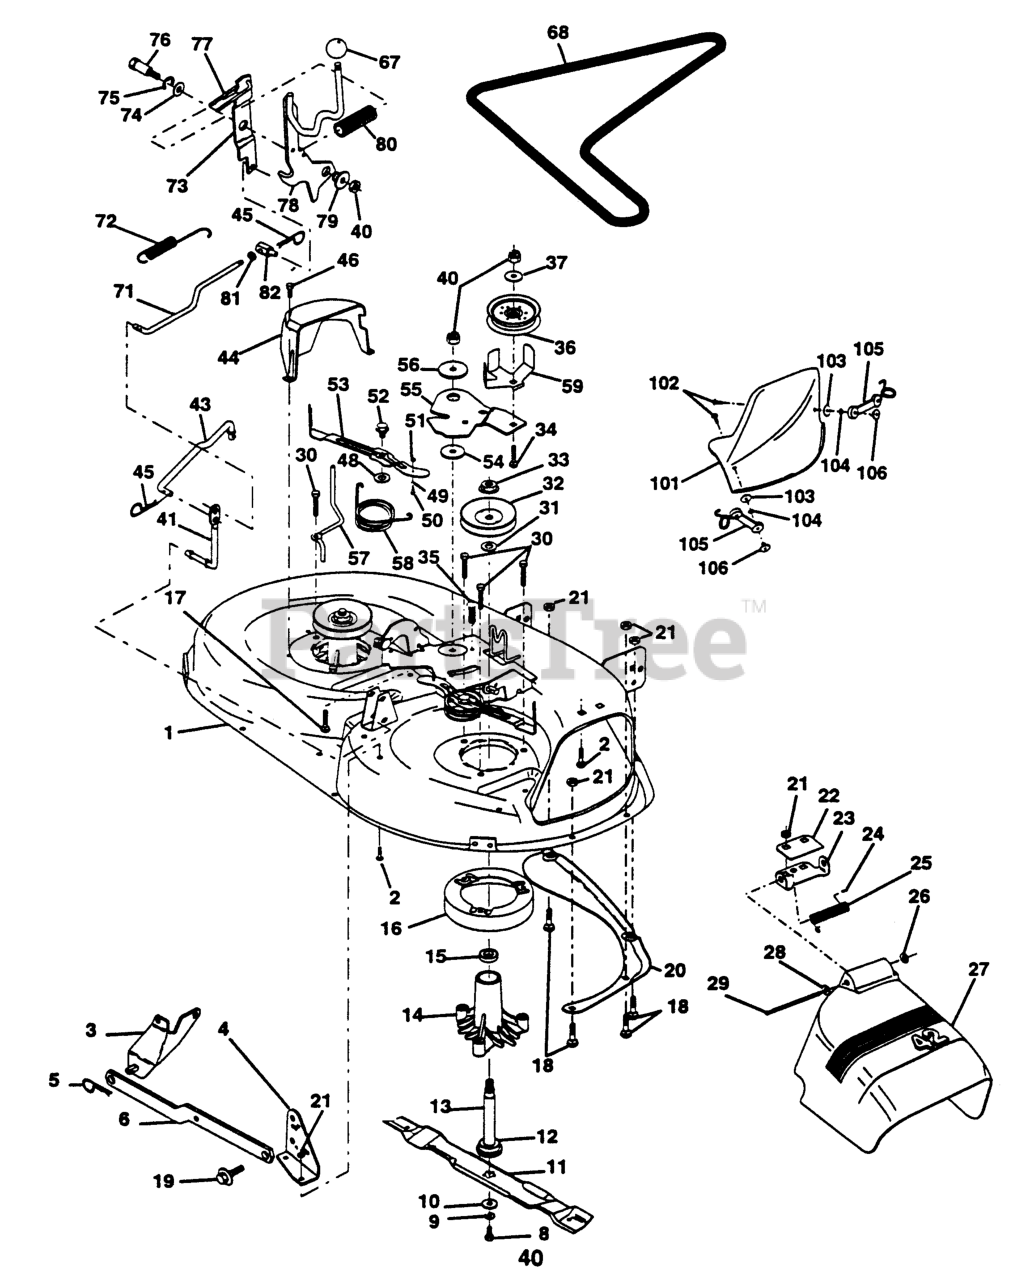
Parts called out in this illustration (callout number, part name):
1	DECK 42"
2	RP BOLT 5/16-18 X3/4 ZN/YEL GR
3	BRKT ASM SWAY BAR
4	BRKT DECK SW BAR
5	RETAINER-SPRNG RB
6	REAR SUSP ARM
7	NUT.71038.31-18.HEX.NYLOCK
8	BLADE BOLT
9	LOCKWASHER
10	WASHER.BLADE
11	BLADE.42".MULCH
12	BEARING.BALL.#6204.(MANDREL)
13	SHAFT ASM VENT
14	HOUSING.MANDREL.VENTED (MACHD)
16	STRIPPER
17	BOLT
18	BOLT
19	BOLT SHD 5/16-18
20	BAFFLE
21	Nut Crown Lock 5/16-18 Unc
22	STIFFENER BRACKET
23	DEFLECTOR BRACKET
24	CAP-SLEEVE LT
25	SPRING TORSION
26	NUT PUSH M
27	SHIELD.DEFLECTOR.MOWER.42".BLK
28	Washer 11/32 X 5/8 X 16 Ga
29	ROD.HINGE
30	SCREW
31	WASHER
32	MANDREL PULLEY
33	NUT
35	FASTENER.XMAS.TREE
36	FLAT IDLER PULLEY
37	WASHER
40	NUT
43	CLUTCH ROD
44	GUARD MANDREL LH BLACK
45	RETAINER M
46	SCREW.1/4-20X5/8
49	CAM FOLLOWER
52	BOLT.SHOULDER.5/16-18
53	ARM
54	HARDENED WASHER
55	IDLER ARM
56	SPACER RETAINER
59	GUARD, BELT
67	KNOB T (1/2-HOLE)
68	V-BELT TRIPATH
71	CLUTCH ROD
72	RETURN SPRING
73	ARM CLUTCH SECONDARY
77	KEEPER SPRING
78	CLUTCH ARM
79	BUSHING.FLANGE.E-RING.GROOVE
80	SPRING
81	NUT
82	TRUNNION.ADJUSTABLE.3/8-16
84	KEEPER BELT
85	BOLT
101	COVER MULCH 42"
102	SCREW
104	LOCKWASHER #10
105	LATCH ASSEMBLY
106	WELDNUT
